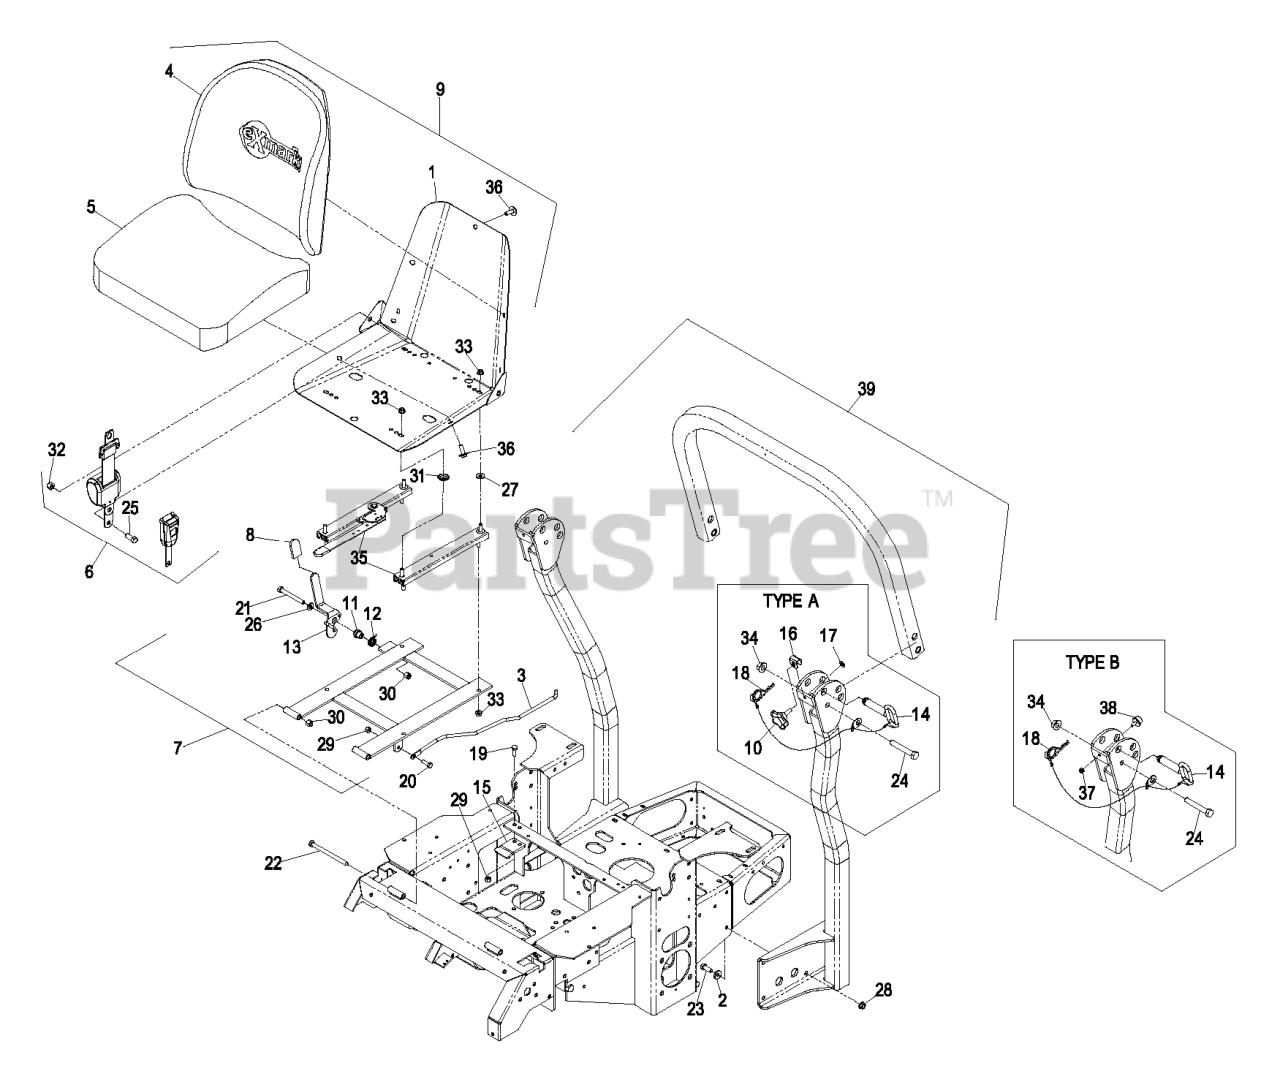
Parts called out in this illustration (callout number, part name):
1	FRAME-SEAT
2	WASHER-BELLEVILLE
3	ROD-RETAINER, SEAT
4	CUSHION,SEAT BACK
5	CUSHION,SEAT BOTTOM
6	RETRACTABLE SEATBELT KIT
7	ASM,SEAT FRAME
8	GRIP-LEVER
11	BUSHING-LATCH, SEAT
12	SPRING-TORSION
13	LATCH ASM
14	PIN-FOLD, ROPS
15	CATCH-LATCH, SEAT
17	NUT-PUSH
18	HAIRPIN
19	SCREW-HH
20	SCREW-HH
21	SCREW-HH
22	SCREW-HH
23	SCREW-HH
24	SCREW-HH
25	SCREW-HH
26	WASHER-FLAT
27	WASHER-FLAT
28	NUT-HHF, WHIZ
29	NUT-LOCK, NI
30	NUT-LOCK, NI
31	SPACER-TRACK
32	NUT-LOCK
35	TRACK-SEAT
36	BOLT-SEAT
37	NUT-LOCK, NI
38	BUMPER-RUBBER
39	KIT, LAZER HP / CT 2 POST
